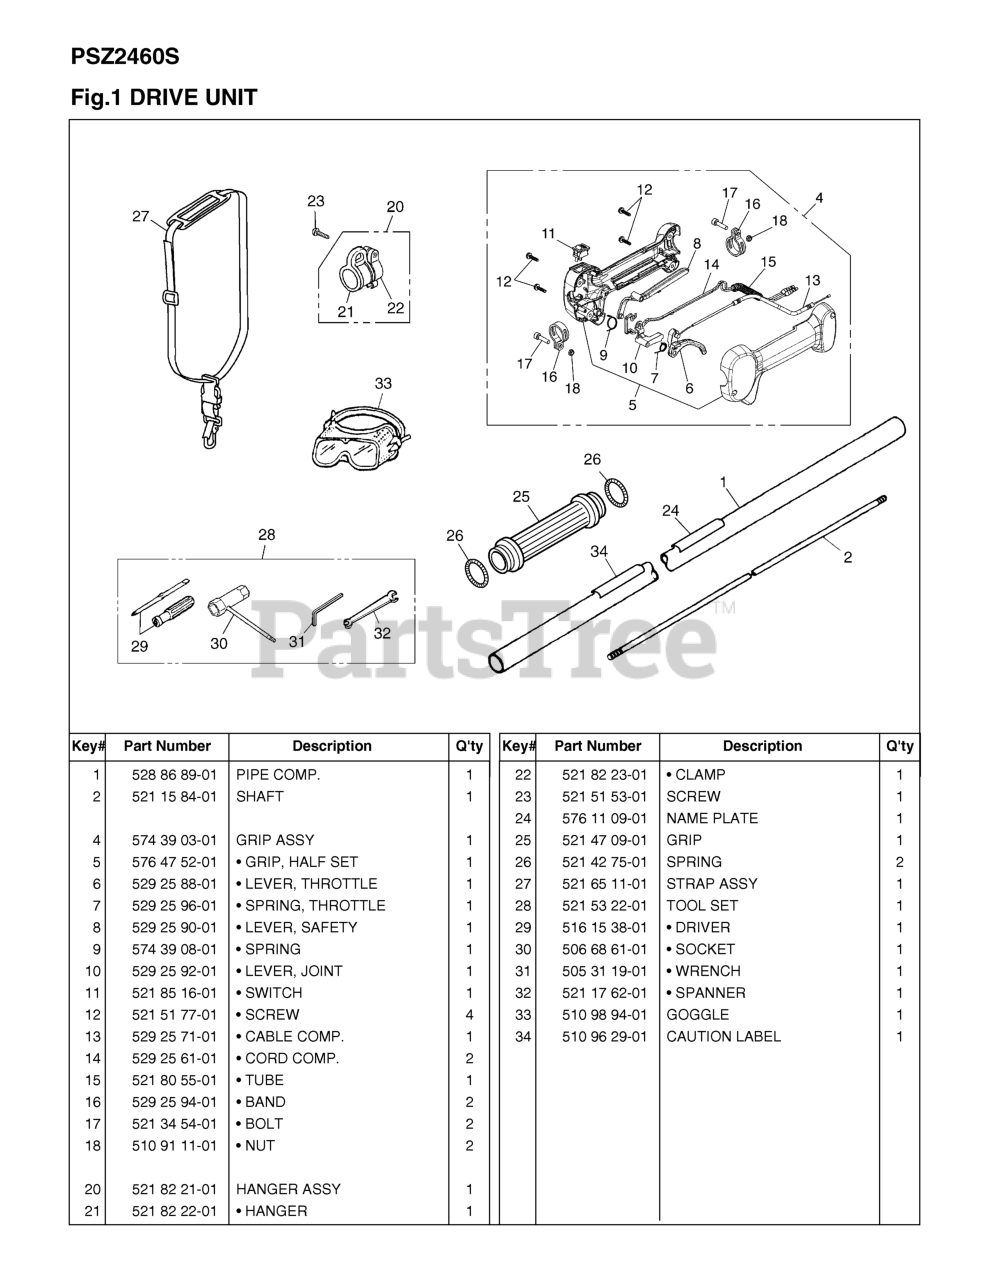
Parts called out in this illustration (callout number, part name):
1	PIPE COMP.
2	SHAFT (RPLS -122
4	GRIP ASSY
5	GRIP, HALF SET
6	LEVER, THROTTLE
7	SPRING, THROTTLE
8	LEVER FOR GRIP (
10	LEVER JOINT
14	CORD - C
17	BOLT (RPLS 28501
18	NUT
20	HANGER COMP.
21	HANGER
24	NAME PLATE
25	GRIP
26	SPRING
27	STRAP ASSY
28	TOOL-SET
29	SCREWDRIVER
32	SPANNER,8 x 10(R
33	GOGGLExxx (RPLS
34	LABEL CAUTON FOR
